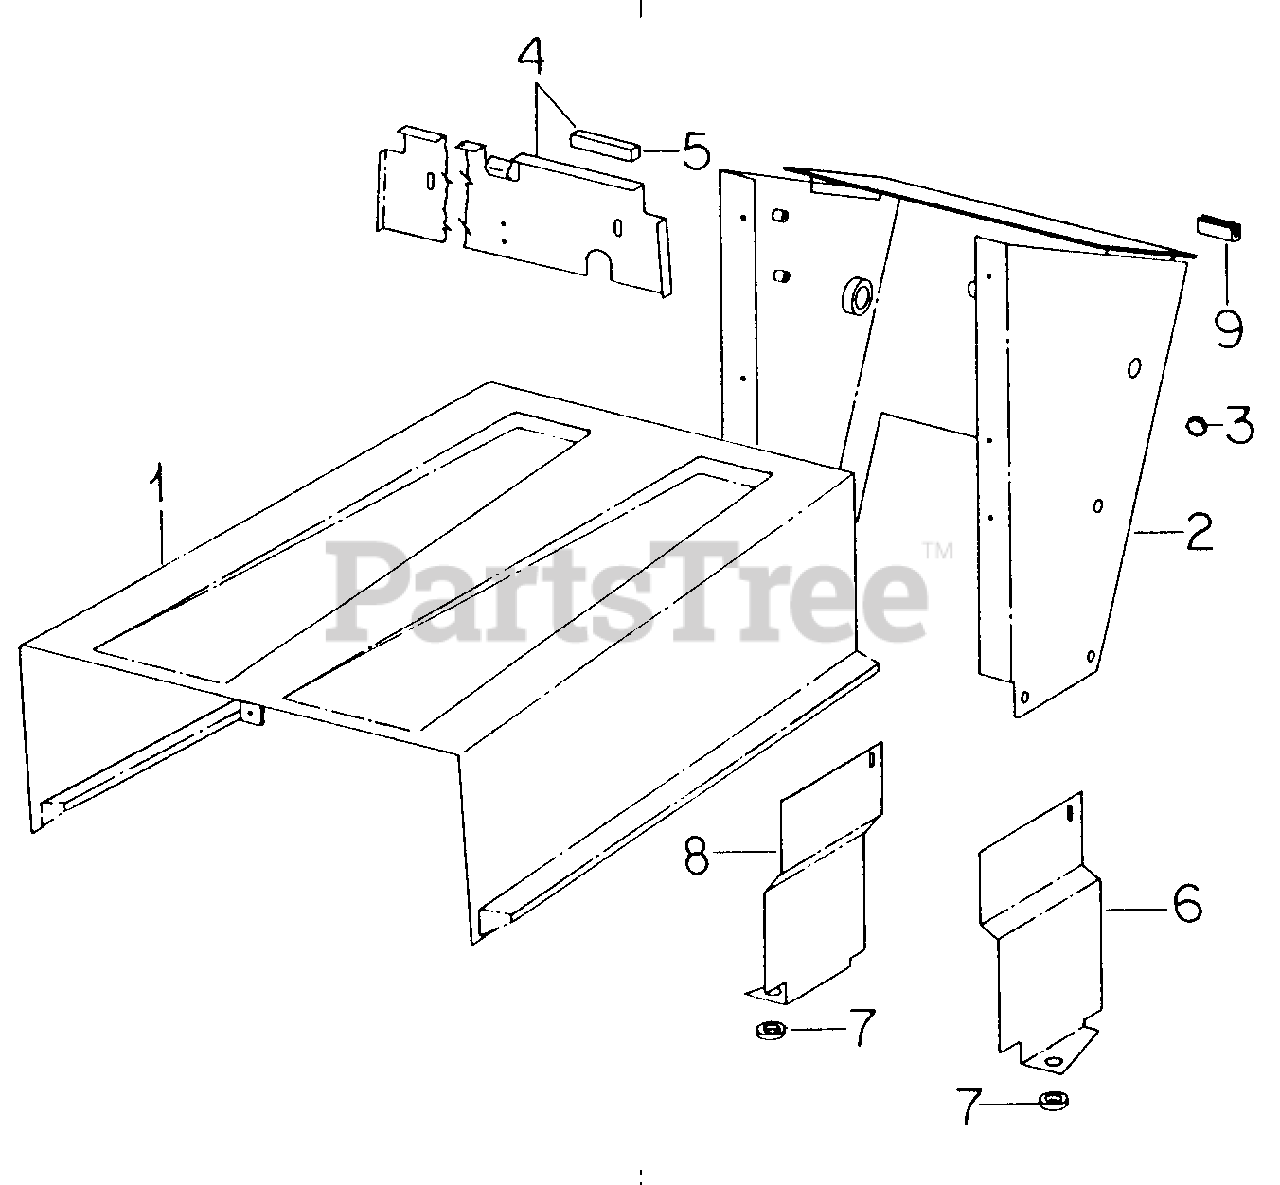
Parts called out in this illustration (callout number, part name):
2	Pedestal Assy, Instrument Panel
3	Plug, 23/32 Button
4	Support Assy, Rear Hood
5	Strip, Hood, Bumper
6	Panel, Extension LH
7	Washer, Rubber
8	Panel, Extension RH
9	Grommet, Edge
